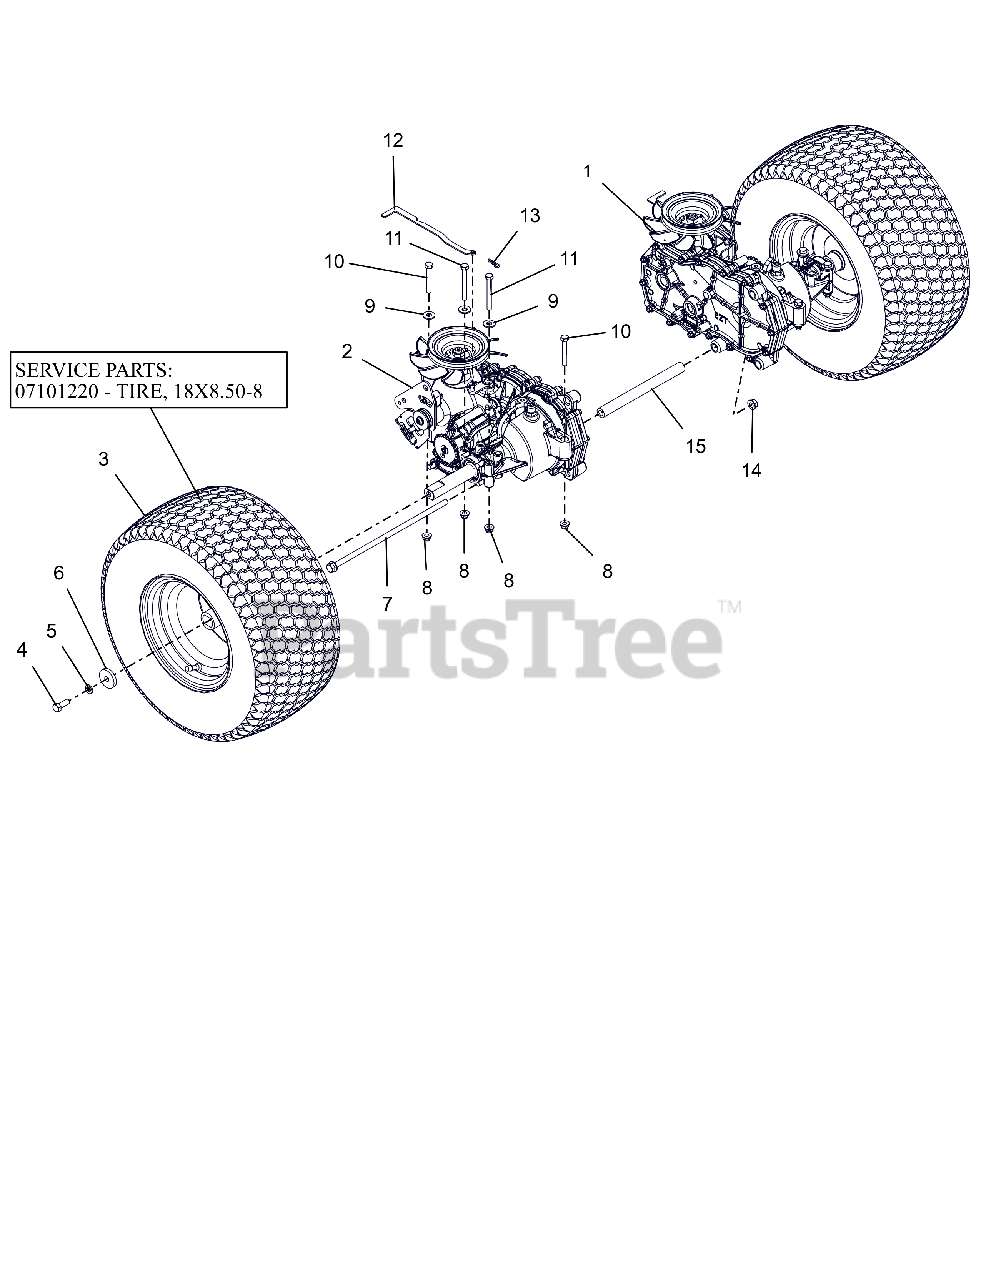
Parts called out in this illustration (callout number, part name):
1	TRANSAXLE EZT D-SHFT SHORT
2	TRANSAXLE EZT D-SHFT SHORT
3	ASM, WHL/TIRE 18X8.50-8 DHUB
3	TIRE, 18X8.50-8
3	TUBE 18X9.50-8
4	BLT, HEX .38-16X1.00 G8ZCCEP30
5	WSHR,LK-REG .375X.094 ZCC
6	WSHR, FLT .406X1.50X.245 ZCC
7	BLT,HEX-FLG .38-16X11.5 G5 ZCC
8	NUT,LK-NYL-FLG .31-18 G5ZC120
9	WSHR,FLT .375X.875X.083 ZCC
10	BLT, HEX .31-18X2.25 G5 ZCC
11	BLT, HEX .31-18X2.75 G5 ZCC
12	BRKT, DUMP VALVE
13	PIN, HAIR #213 .08X1.19 ZCC
14	NUT-LK-CTR-FLG .375-16 GF ZCC
15	TUBE, TRANSAXLE BRACE 8.18LG
